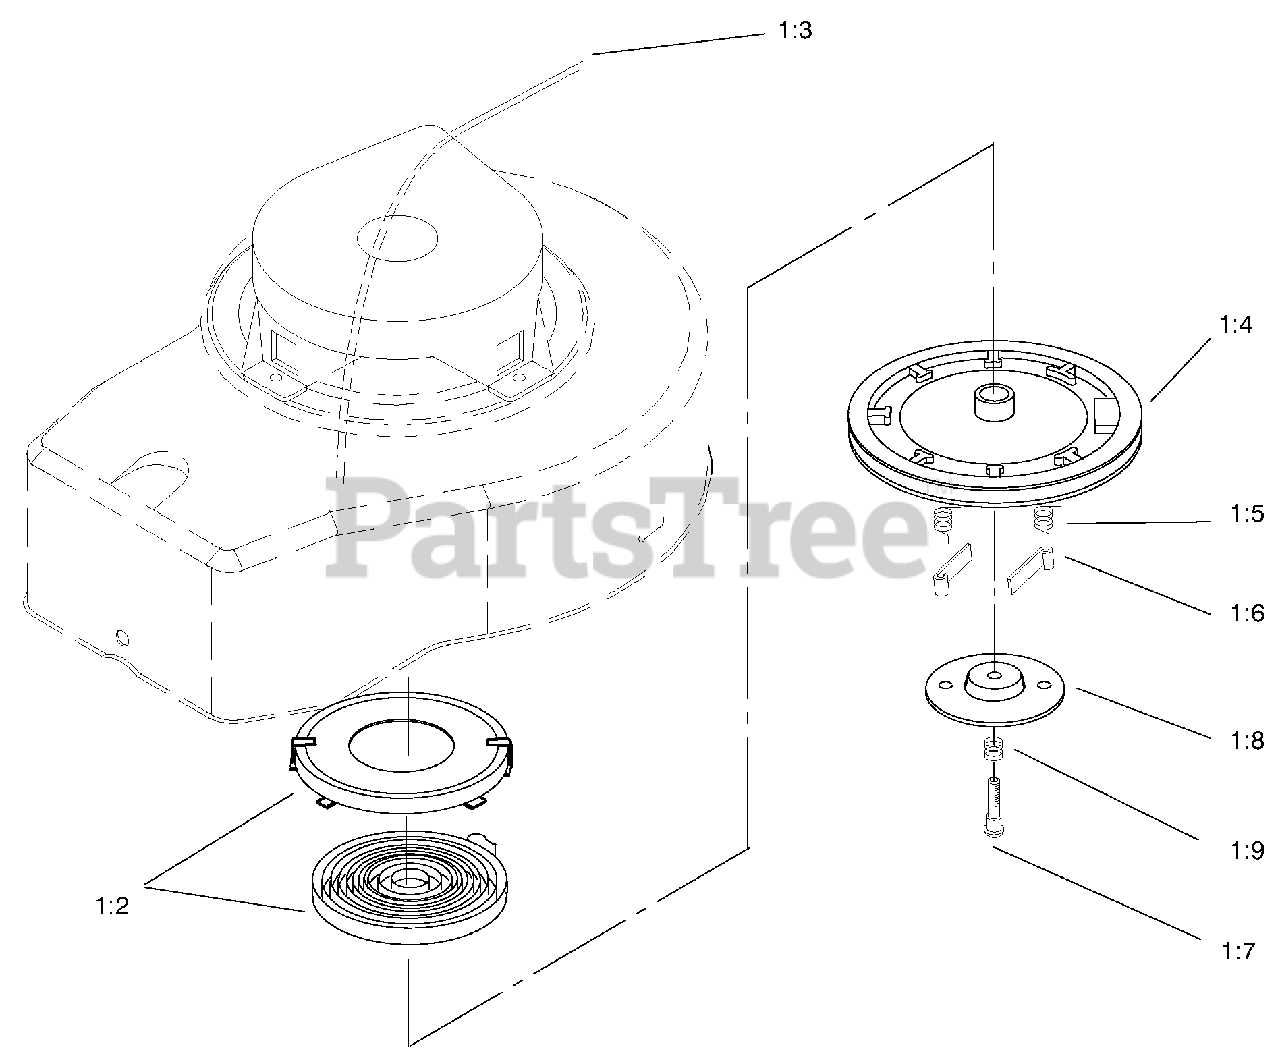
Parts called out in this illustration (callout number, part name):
1:2	ASM-Keeper
1:3	88 5/8 Grey Rope
1:4	ASM-Pulley
1:5	Spring-Dog
1:7	Spring-Brake
1:8	Retainer
1:9	Screw-Center
